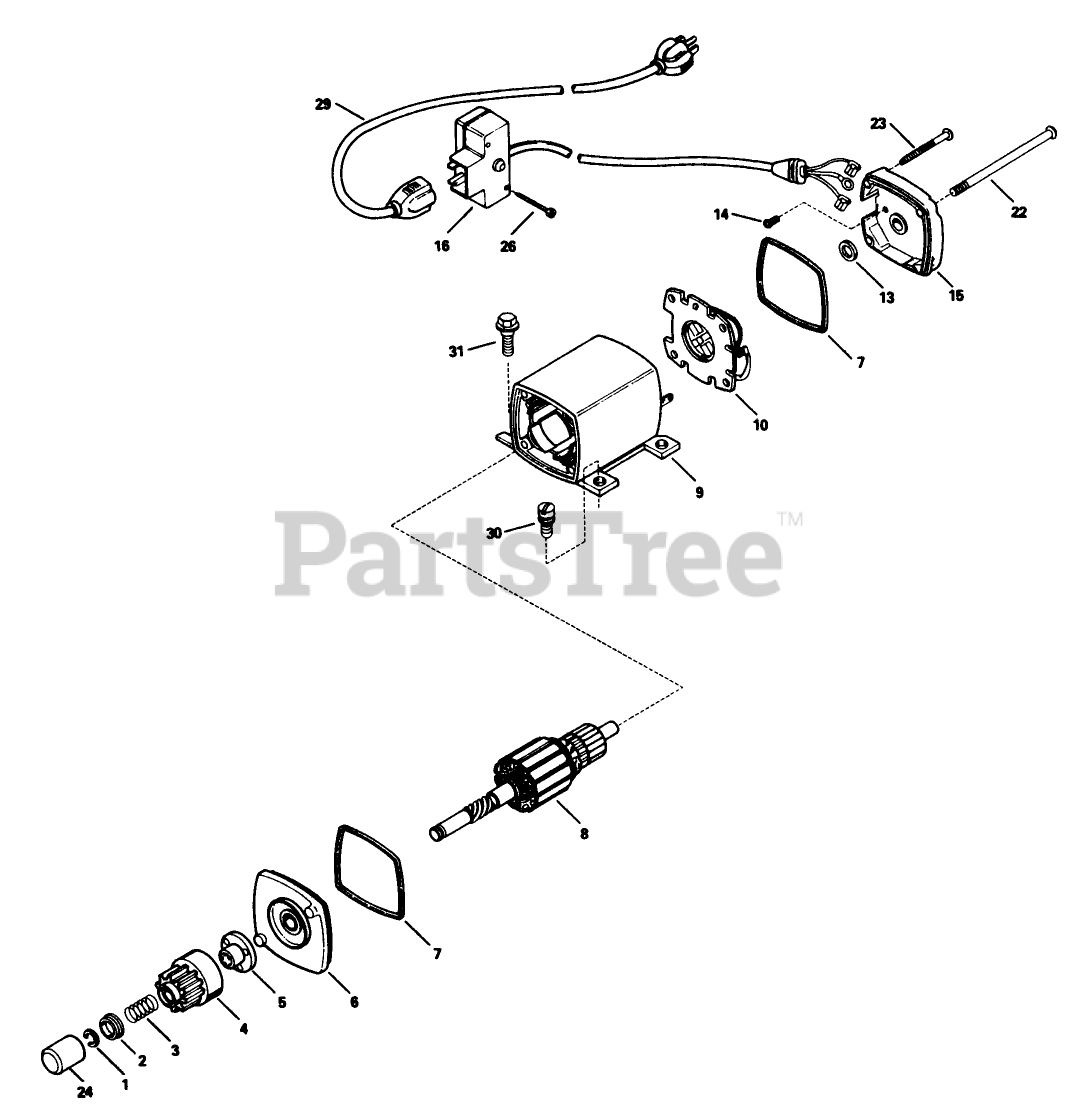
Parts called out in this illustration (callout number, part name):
1	Ring-Retainer
2	Retainer-Spring
3	Spring-Anti Drift
4	Gear
5	Nut-Engaging
6	Cap Assembly-Cap End (Incl. Ref. #7)
7	O-Ring
8	Armature
9	Housing Assy.
10	Card ASM
13	Washer-Thrust
14	Screw-Ground
15	Cap Assembly Commutator End (Incl. Ref. #7)
16	Box Assembly-Switch (Incl. Ref. #26)
22	Bolt-Case
23	Screw-Ground
24	Cover-Dust
26	Screw
29	Cord-Extension
30	Screw
31	Screw (1/4-20x1/2)
